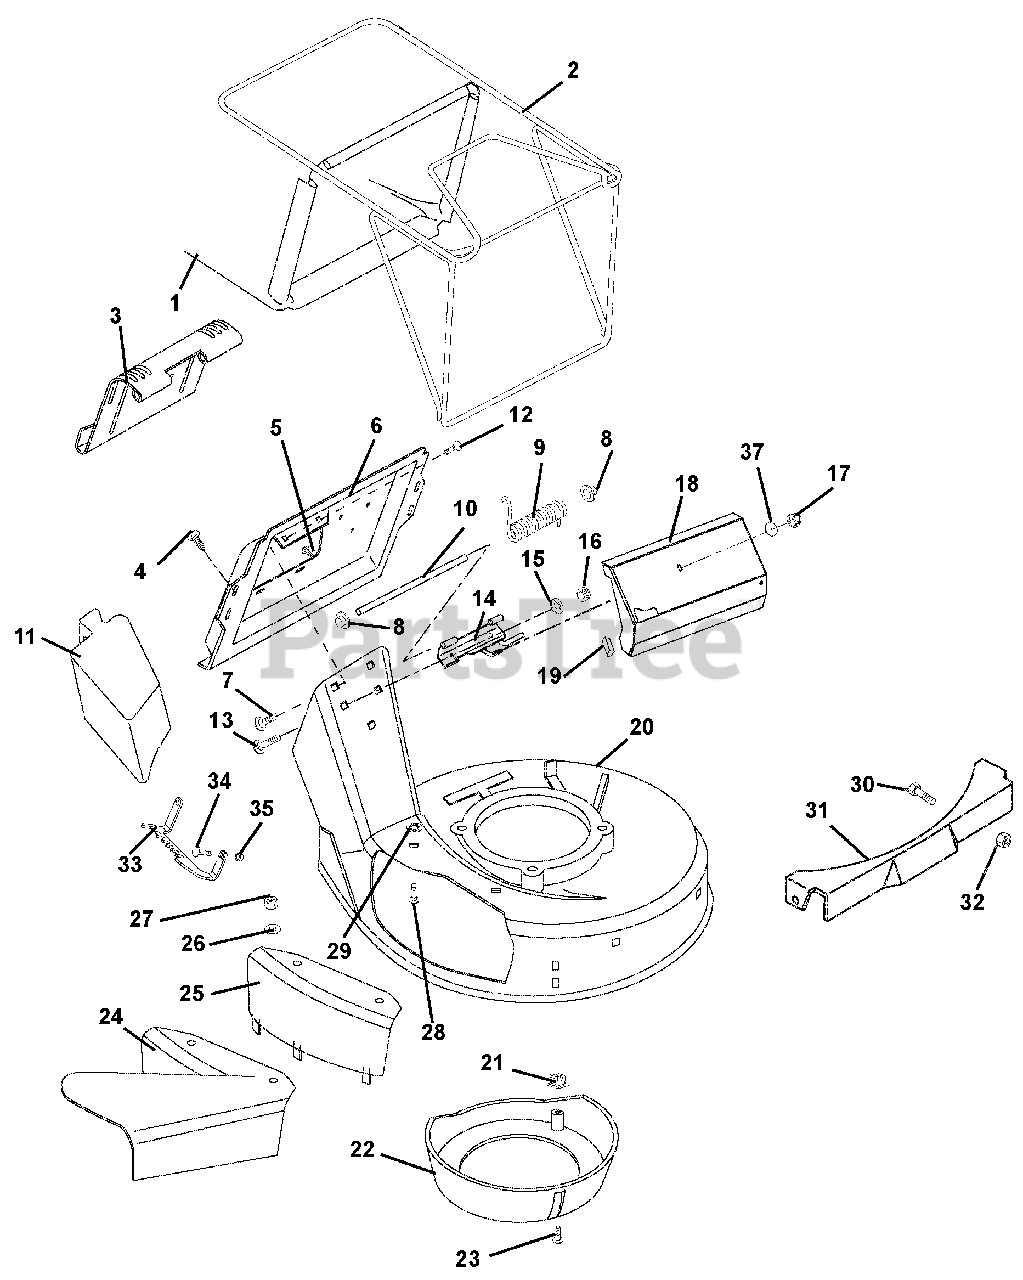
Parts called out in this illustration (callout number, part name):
1	BAG, CONSUMER BLACK 15 OZ/YD2
2	FRAME, WBLM BAGGER
3	CATCHER PLATE DOOR
4	@SCR-TAP 12-24X.50 HWH TR YWZC
5	SCR-TAP 10-24X.375 TORX PHD YZ
6	CATCHER PLATE
7	@BLT-RHDSSQNK .25-20X.38 G2YZ
8	PUSH NUT, .25
9	SG-TORS .120X.68X3.09
10	DOOR PIN
11	MULCH MASTER PLUG
12	@NUT-SPNLK-FLG .25-20 YWZC
13	@BLT-RDHDSQNK .25-20X.75 G5YZ
14	HINGE BASE WELDMENT
15	WSHR-LK .250X.077 HVY YWZC
16	@NUT-HEX .25-20 YWZC
17	@NUT-LK-NYL-FLG .25-20 YWZC
18	COVER, LM BRIGGS CE DRIVE
18	COVER, LM DRIVE
19	TRIM BUMPER
20	MOWER PAN HEAD W/SFTYDECALS SP
21	PLASTIC GROMMET
22	CENTER BAFFLE
23	SCR-TAP 10-16X.62 SLPH AB YWZC
24	SIDE DISCHARGE ASSEMBLY
25	COVER, SIDE DISCHARGE
26	@WSHR-FL-STL.406X.812X.065 YWZ
27	@NUT-LK-NYL .312-18 YWZC
28	@BLT-RHDSSQNK .31-18X.75 G5YZ
28	@BLT-RDHDSQNK .31-18X.75 G5YZ
29	NUT-PUSH .312
30	@BLT-RDHDSQNK .31-18X.50 G5YZ
31	PANEL-FRONT
32	@NUT-LK-TOP-FLG .31-18 YWZC
33	BRKT, SPD SELECTION
34	@BLT-RDHDSQNK .25-20X.50 G5YZ
35	@NUT-LK-CTR .25-20 YWZC
36	@WSHR-FL-STL.281X.62X.065 YWZC
37	WSHR-FL-NY .375X.75X.060
